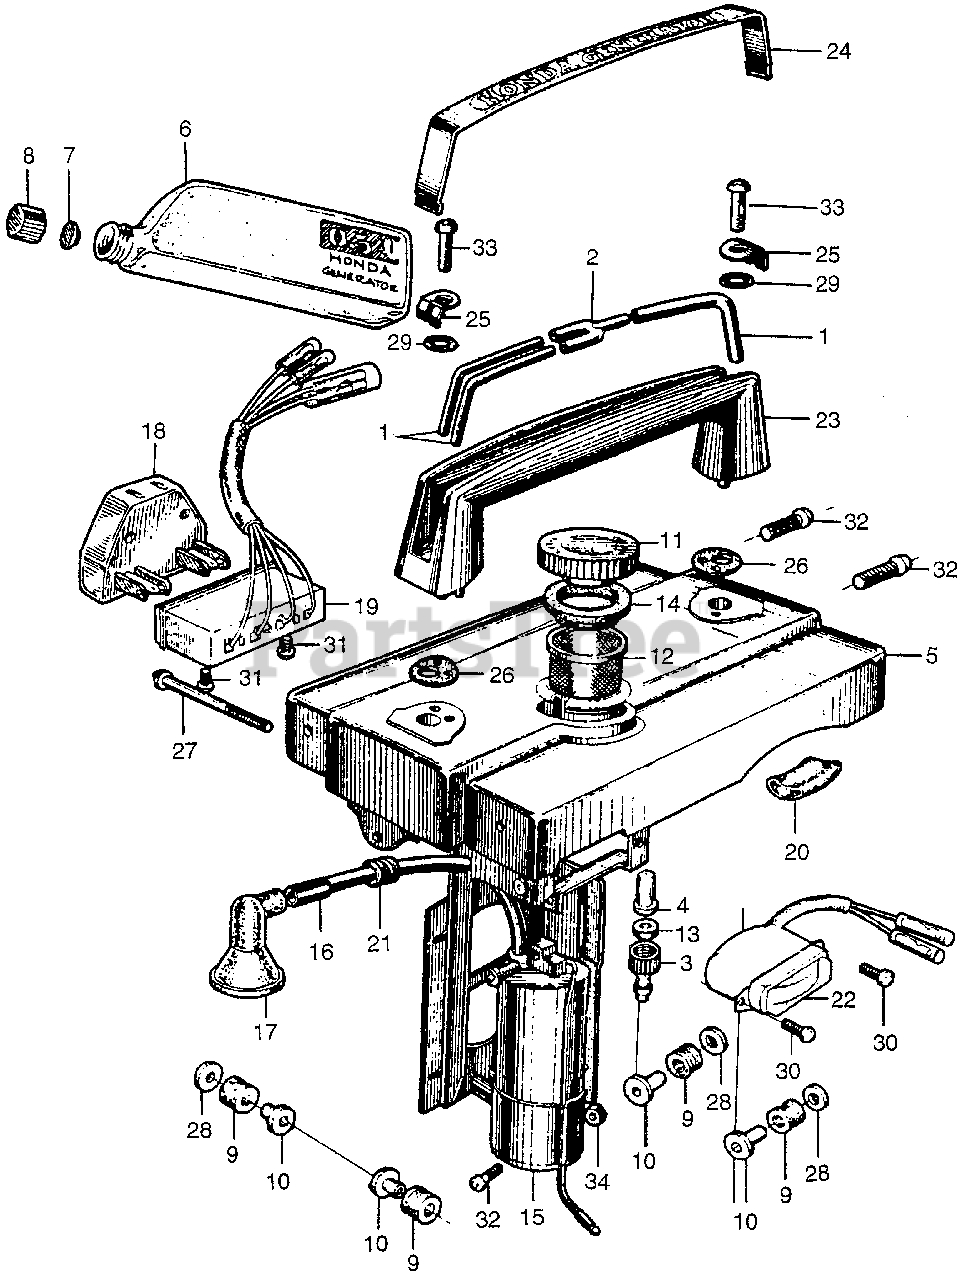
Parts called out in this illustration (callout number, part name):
1	TUBE, BREATHER (NOT AVAILABLE)
2	TUBE, BREATHER (NOT AVAILABLE)
3	BODY, STRAINER (NOT AVAILABLE)
4	FILTER, CHECK (NOT AVAILABLE)
5	TANK, FUEL *NH2M* (METALLIC SILVER) (NOT AVAILABLE)
6	SUB-TANK, FUEL
7	INNER CAP, FUEL TANK (NOT AVAILABLE)
8	CAP, SUB-TANK (NOT AVAILABLE)
9	DAMPER, TANK STAY (NOT AVAILABLE)
10	COLLAR, TANK DISTANCE (NOT AVAILABLE)
11	CAP, TANK (NOT AVAILABLE)
12	FILTER, FUEL (NOT AVAILABLE)
13	GASKET, ELEMENT SEALED (NOT AVAILABLE)
14	RUBBER, FILTER (NOT AVAILABLE)
15	COIL, A.C. IGNITION
15	COIL, A.C. IGNITION (NOT AVAILABLE)
16	TERMINAL, IGNITION (NOT AVAILABLE)
17	CAP, IGNITION TERMINAL (NOT AVAILABLE)
18	ADAPTER (250V 10A) (NOT AVAILABLE)
19	RECEPTACLE ASSY., DOUBLE (NOT AVAILABLE)
20	COVER, BINDER
21	GROMMET, WIRE (NOT AVAILABLE)
22	VOLTMETER (117V) (NOT AVAILABLE)
23	GRIP (NOT AVAILABLE)
24	COVER, GRIP (NOT AVAILABLE)
25	HOOK, GRIP COVER
26	GASKET, GRIP (NOT AVAILABLE)
27	SCREW, TANK SETTING (NOT AVAILABLE)
28	WASHER, STOPPER
29	O-RING (5X1.5) (NOT AVAILABLE)
30	SCREW, PAN (3X6) (NOT AVAILABLE)
31	SCREW, PAN (3X14) (NOT AVAILABLE)
32	SCREW, PAN (5X18)
33	SCREW, PAN (6X18)
34	NUT, HEX. (5MM)
